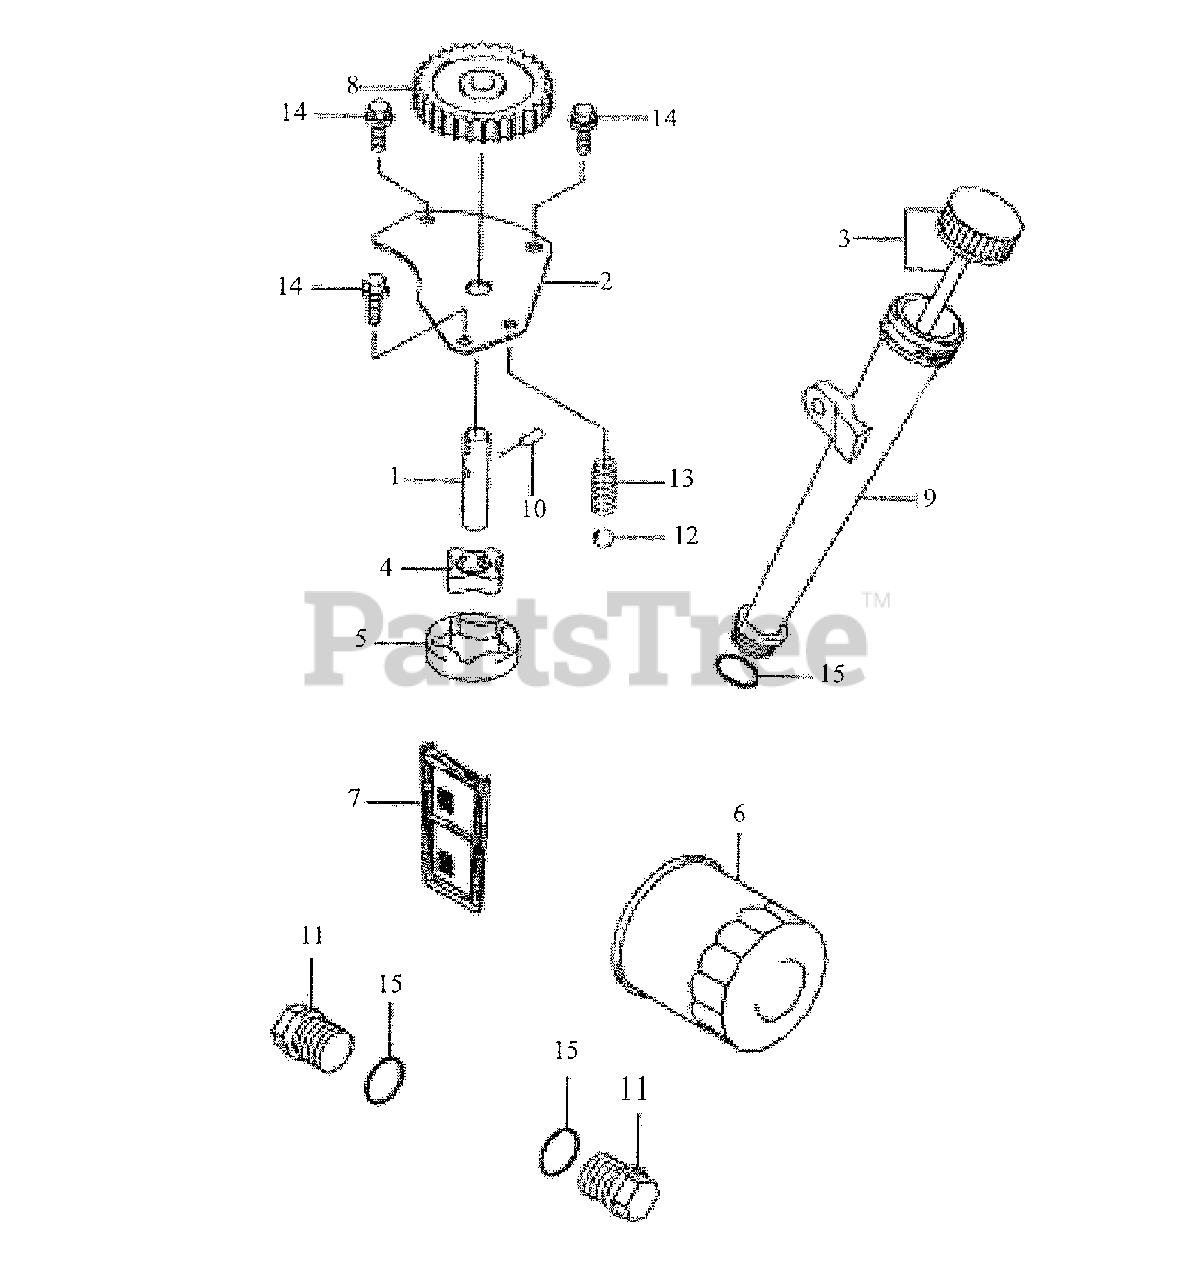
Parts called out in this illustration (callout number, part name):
1	Shaft, Oil Pump
3	Cap-Assembly
4	Rotor-Pump In
5	Rotor-Pump Out
6	Filter-Oil
8	Gear-Spur
9	Filler Tube
10	Pin
11	Plug
14	Bolt-Flange
